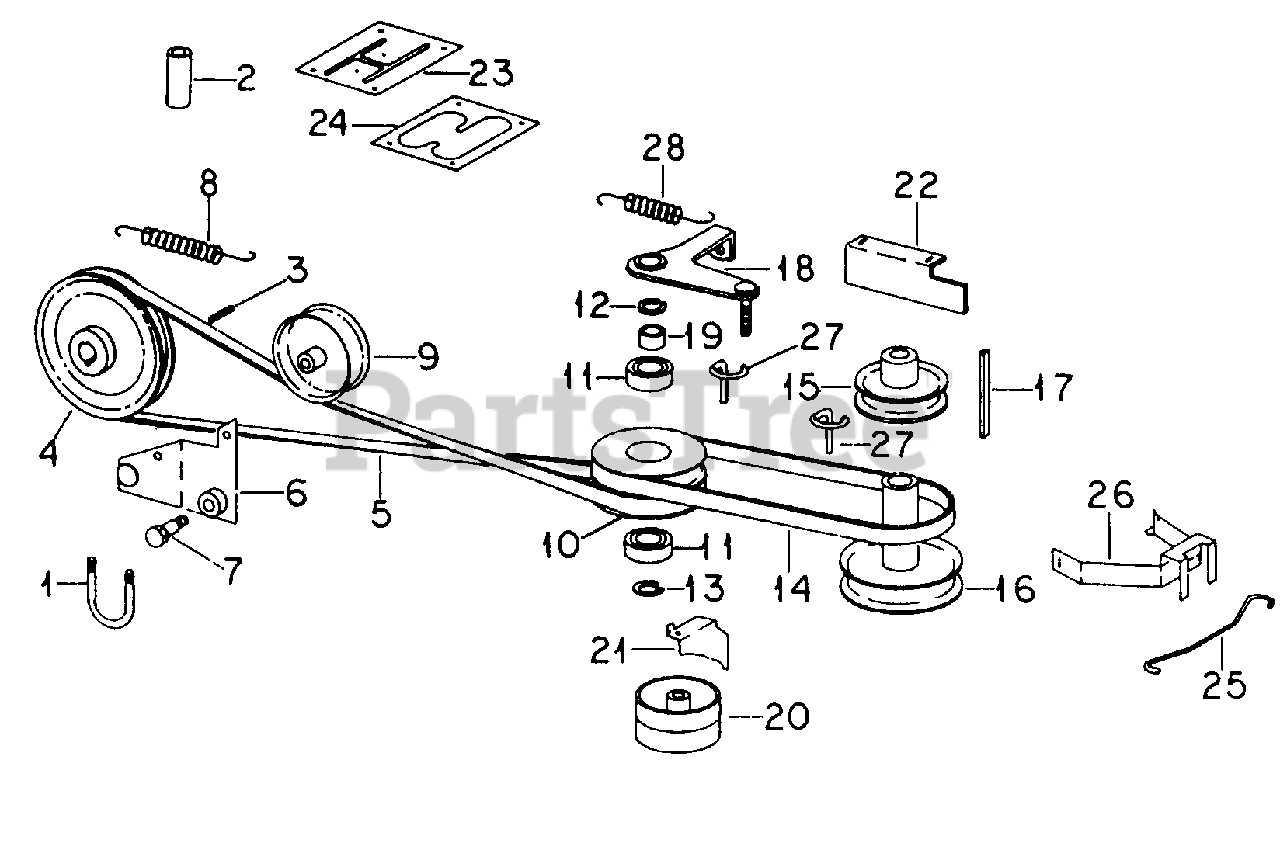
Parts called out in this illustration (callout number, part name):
2	Spacer, Transaxle Mounting
3	Key, 3/16 x 3/4 SAE 9 Woodruff
4	Pulley, Transaxle
5	Belt, Mower & Final Drive
6	Arm Assy, Belt Tensioning
7	Bolt, IPTO Shoulder
8	Spring, Extension, 5.5 In. Long, 48 Coils
9	Pulley, Final Drive Idler
10	Pulley, Intermediate Drive
11	Bearing, Intermediate Pulley
12	Ring, External Retaining
13	Ring, Internal Retaining
14	Belt, Clutching
15	Pulley, Engine Drive
16	Pulley, Mower Drive, 5-1/4 In. Diameter
17	Key, 1/4 x 2-3/4 Sq Parallel
18	Bushing Assy, Clutch
19	Bushing
20	Pulley, Mower Shifter Idler
21	Guide, Belt
22	Guide, Belt
23	Cover, Gear Shift Hole
24	Plate, Gear Shift Hole
25	Support, Belt Guide
26	Guide, Engine Belt
27	Guide, Transaxle Belt
28	Spring, Extension, 4.9 In. Long, 30 Coils
